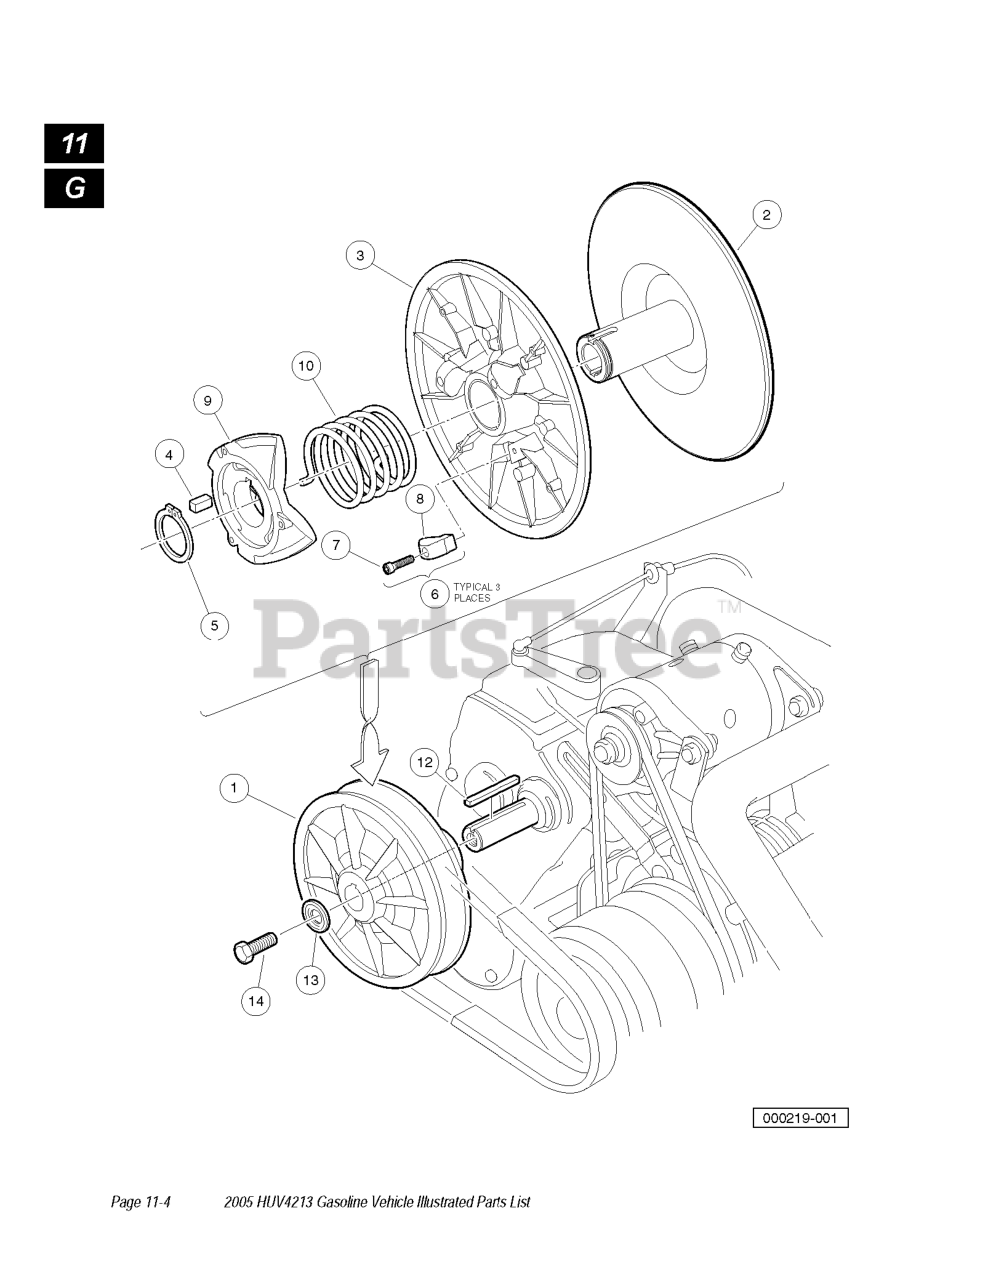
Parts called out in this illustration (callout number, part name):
1	DRIVEN CLUTCH ASM - FE290D
2	FIXED FACE ASSY
3	MOVEABLE FACE ASSY
4	KEY, DRIVEN CLUTCH
6	KIT, DRIVEN CLUTCH BUTTON
7	SCREW, #8-32 X 3/4 SOC HD CAP
9	CAM, DRIVEN CLUTCH
10	SPRING, DRIVEN CLUTCH REVERSED
11	WASHER, DRVN CLUTCH BELLEVILLE
12	KEY, 3/16 SQ X 1.50"
14	SCREW, 5/16-18X3/4 HX HD W/PTC
